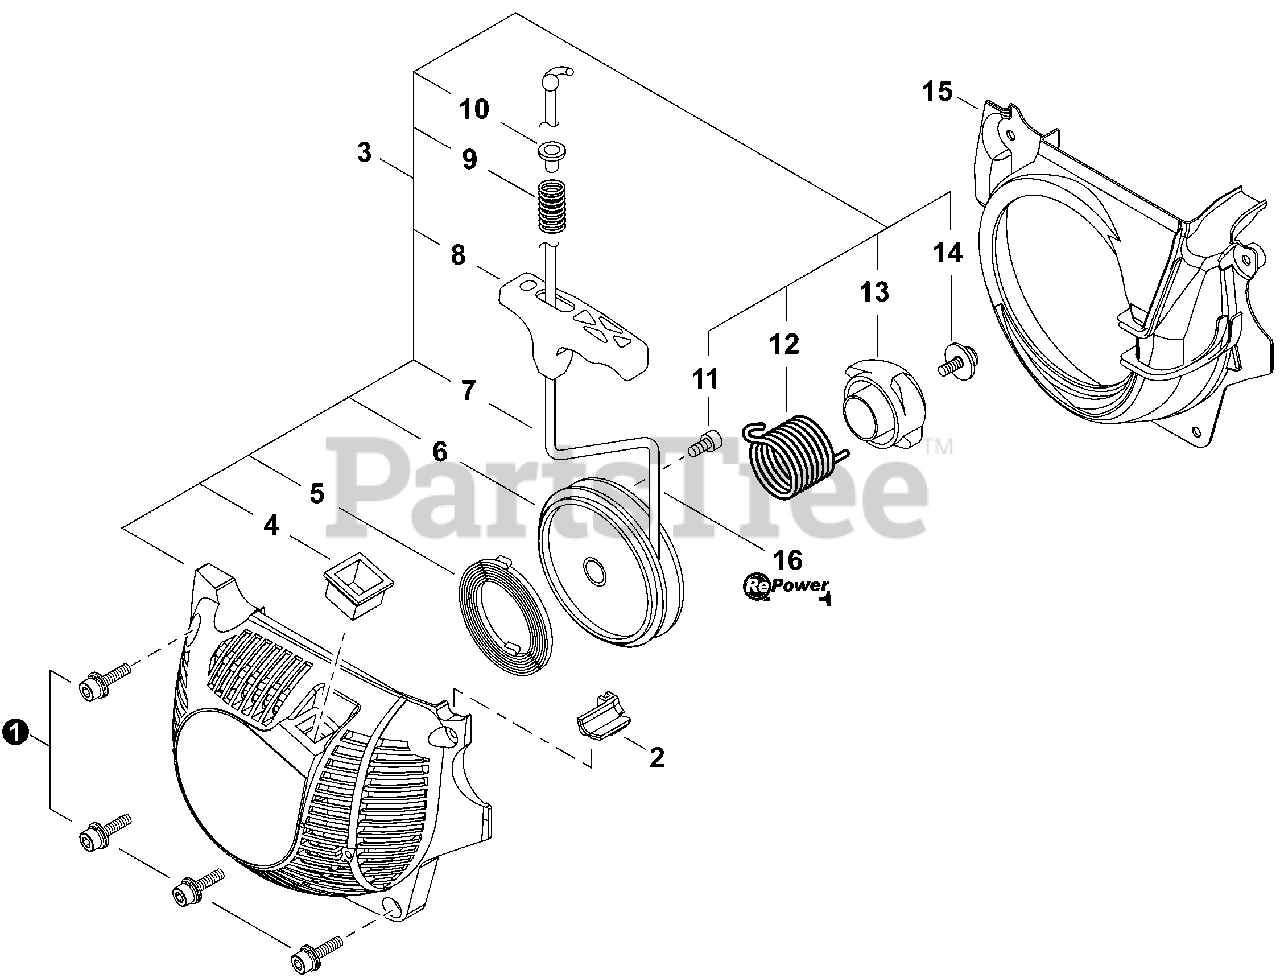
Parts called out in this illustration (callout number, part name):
1	BOLT M4×16
2	GROMMET, NEEDLE
3	STARTER ASSY, RECOIL
4	GUIDE, ROPE
5	SPRING
6	REEL, ROPE
7	ROPE, STARTER
8	GRIP, STARTER
9	SPRING, COMPRESSION
10	RETAINER, ROPE
11	BOLT 4×10
12	SPRING, TORSION
13	PAWL CATCHER
14	SCREW
15	COVER, FAN
16	ROPE, STARTER - REPOWER BULK
